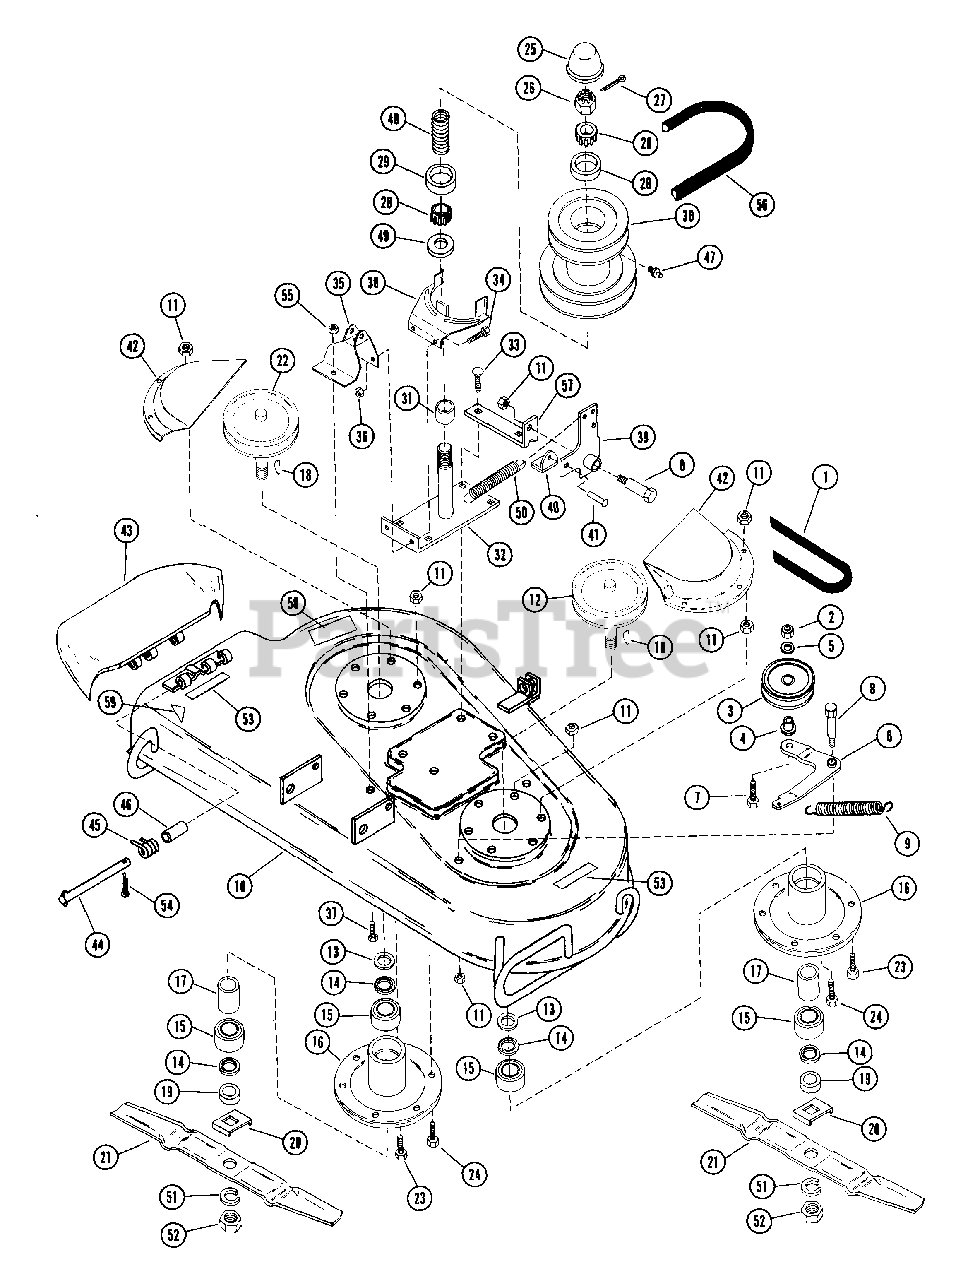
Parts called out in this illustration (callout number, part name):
1	V-BELT, 4L-RAW EDGE
2	NUT-LK-CTR .50-13
3	IDLER-FLAT 2.75X.62
4	BSHG-FLG .500X.625X.500X.750
5	WSHR-FL-STL .505X.880X.072 PL
7	BLT-HEX .50-13X1.25 PL GR2
8	SHOULDER BOLT
9	SG-TENS .091X.73X5.28 WLD 30
10	PAN ASSEMBLY
11	NUT-LK-CTR .375-16 GR A PL
13	WSHR-FL-STL .755X1.250X.125
14	BEARING SLINGER
15	BRG-BALL .751X1.78X.61
16	SPINDLE HOUSING
17	SPACER .753X1.000X1.140
18	KEY-WDRF .188X.75X.313 SAE 9
19	RETAINER HUB
20	BLADE TRAY
21	MOWER BLADE
22	SHEAVE
23	BLT-HEX .38-16X1.00 PL
24	BLT-HEX .38-16X.75 PL GR2
25	CAP, GREASE
26	NUT-JAM SL .75-20 PL
27	PIN-COTR .12 X 1.25 PL
28	BRG-CONE .750X.61
29	BRG-CUP 1.781X.475
30	SHEAVE ASSEMBLY-MOWER
31	SPACER .753X1.000X.625
33	BLT-RDHDSQNK .38-16X.75 SHT PL
34	BLT-SERHFWH .31-18X.75 PL
35	BRACKET
36	NUT-FLG. .312-18 PL
37	BLT-HEX .31-18X.50 PL GR2
41	RVT .25X.50 RH ST
43	PAN CHUTE EXTENSION
44	CLEVIS PIN
45	SG-TORS .095X.50X 1.0
46	BSHG-SLV .334 X .502 X 1.437
47	HYDRAULIC DRIVE FITTING
48	SG-COMP .091X.950X2.062
49	SEAL .750X1.690X.153
50	SG-TENS .072X.50X8.0 WLD 25
51	WSHR-LK .750X.188 MED PL
52	NUT-JAM .75-10 PL
53	WARNING LABEL
54	PIN-COTR .09X.75 PL
55	NUT-LK .312-18 GR A PL
56	V-BELT, 5L-RAW EDGE
57	BRACKET
58	MOWER CAUTION LABEL
59	SAFETY LABEL
